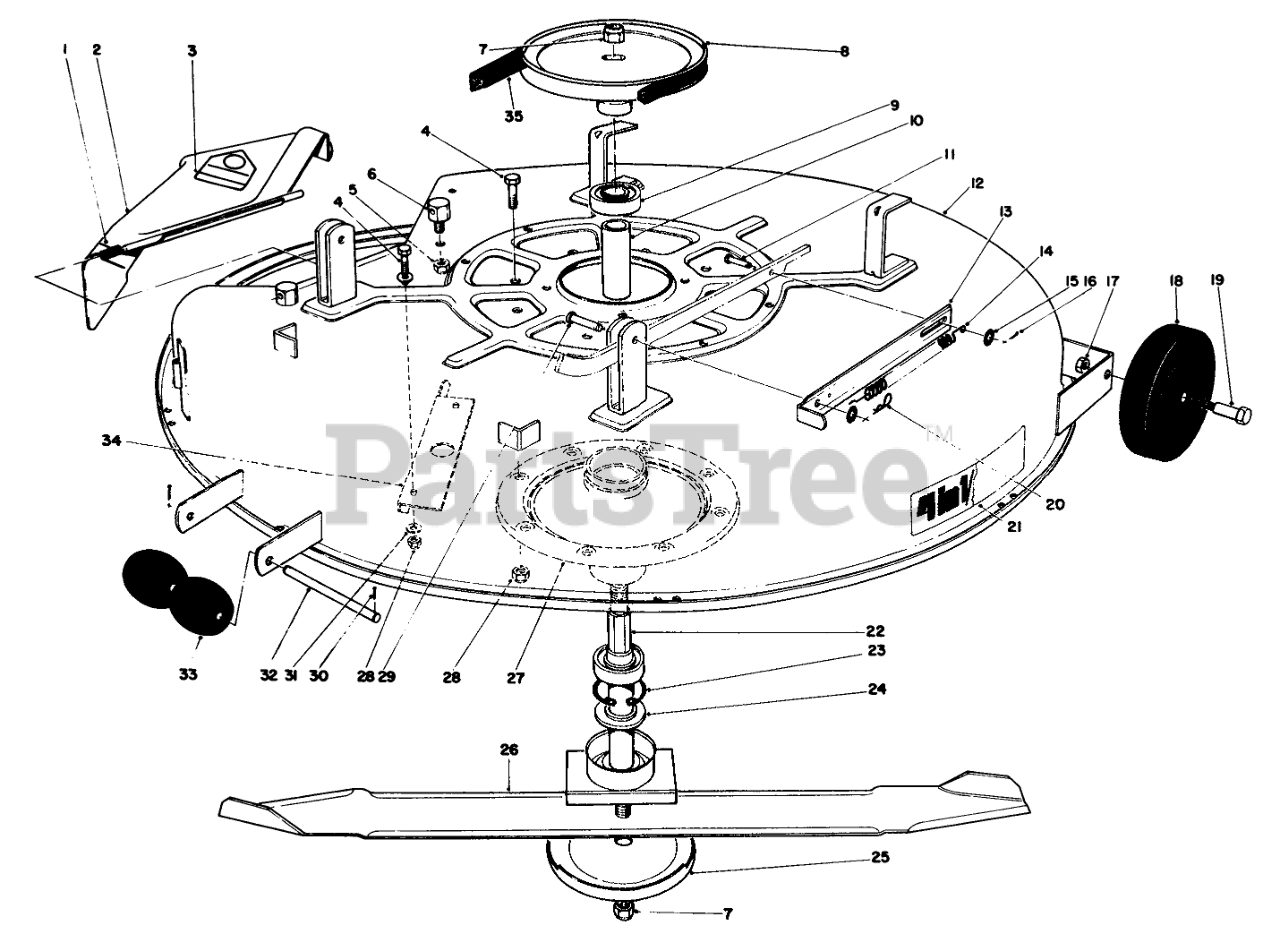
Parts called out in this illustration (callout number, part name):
1	SPRING
2	Deflector Assembly (Incl. Ref. #3)
3	DECAL-DANGER
4	SCREW-HH
5	NUT-LOCK, SIDE
6	POST-PIVOT
8	PULLEY(BLADE DRIVE)
9	BEARING-BALL
10	Spacer-Bearing
11	PIN-CLEVIS
13	DECK SPRING STRAP R
14	DECK TENSION SPRNG O
15	WASHER-FLAT
16	PIN-COTTER
17	NUT-LOCK, NI
18	WHEEL-DECK
19	BOLT-WHEEL
20	PIN-COTTER
21	DECK DECAL
22	SPINDLE SHAFT WA
23	RING-RETAINING
24	SPACER-SPINDLE
25	Cup
26	Blade
27	Spindle Body
28	NUT-LOCK, NI
29	PIN-CLEVIS
30	PIN-COTTER
31	WASHER-PLAIN
32	ROLLER SHAFT
33	ROLLER
34	Baffle Deck
35	V BELT
